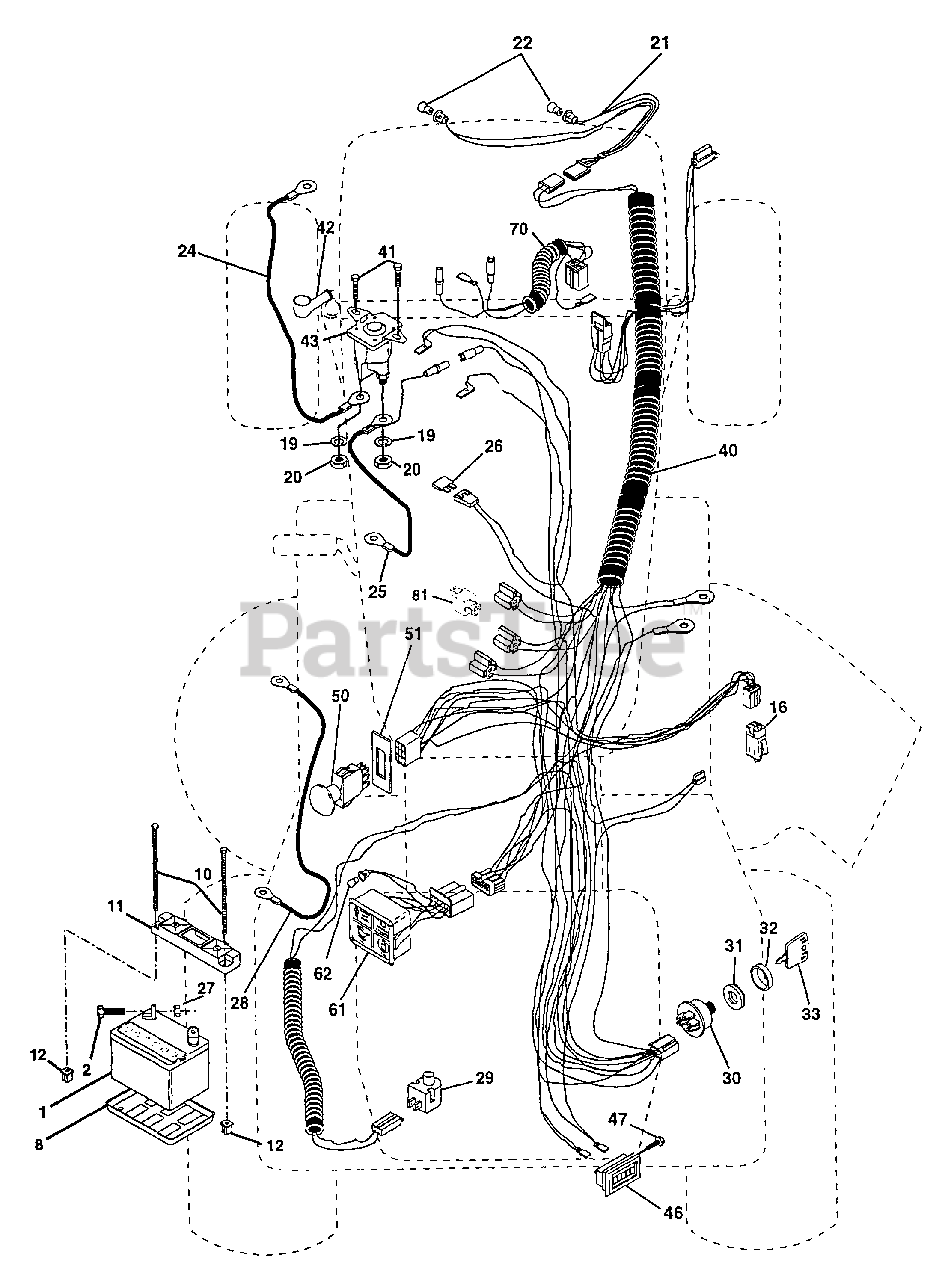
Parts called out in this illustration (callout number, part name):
1	Battery (AYP part number)
2	Bolt Hex Head 1/4-20 x 3/4
8	Tray, Battery
10	Bolt, Battery Front 1/4-20 x 7.5 Zinc (AYP part number)
11	Holddown Battery Front Mount
12	Nut, Push Nylon 1.4" Battery Front (AYP part number)
16	Switch Interlock Push-In (AYP part number)
19	Washer, Lock 1/4 (AYP part number)
20	Nut, Jam Hex 1/4-20
21	Harness Socket Light w/4152J
22	Bulb Light
24	Cable, Starter
25	Cable, Battery (AYP part number)
26	Fuse
27	Nut Keps Hex 1/4-20
28	Cable, Ground
29	Switch, Plunger Normal Op Olive
30	Switch, Ign (AYP part number)
31	Nut, Ignition Switch
32	Cover Switch Key
33	Key
40	Harness Ign. (AYP part number)
41	Screw 1/4-20 x 1/2
42	Cover, Terminal Red
43	Solenoid (AYP part number)
46	Meter Hour
47	Screw #10-24 x 1/2
50	Switch, PTO
51	Ring Retainer PTO
61	Light Pkg Asm
62	Bulb, Light Pkg.
81	Relay Asm.
